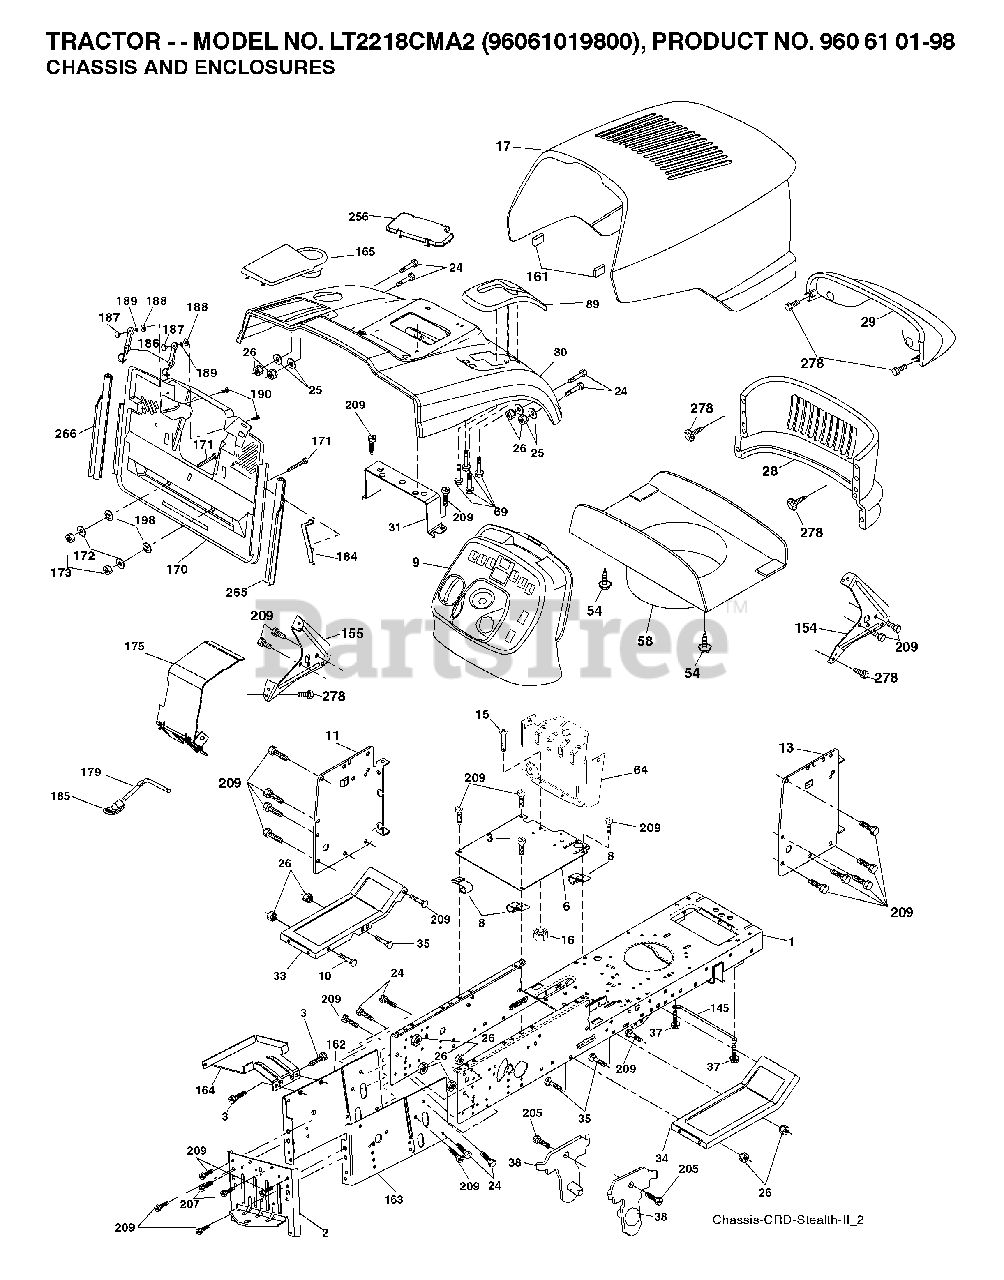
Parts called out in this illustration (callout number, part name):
1	CHASSIS
3	SCREW 3/8-16X3/4
8	CLIP,INSULATOR
10	BOLT D
13	PANEL DASH RH
16	NUT
25	WASHER
26	NUT
31	BRACKET SUPPORT FENDER
54	SCREW.WSHD.HEX10-32X5/8
58	DUCT HOOD
69	SCREW.HI-LO.CONSOLE
145	ROD PIVOT CHASSIS/HOOD
161	EXTRUSION BUMPER
164	SUPPORT
171	BOLT
172	WASHER
186	LATCH ASSY
187	WELDNUT
189	LOCKWASHER
207	SCREW, 5/16-18 X 1/2
209	SCREW, 3/8-16X3/4
278	SCREW
